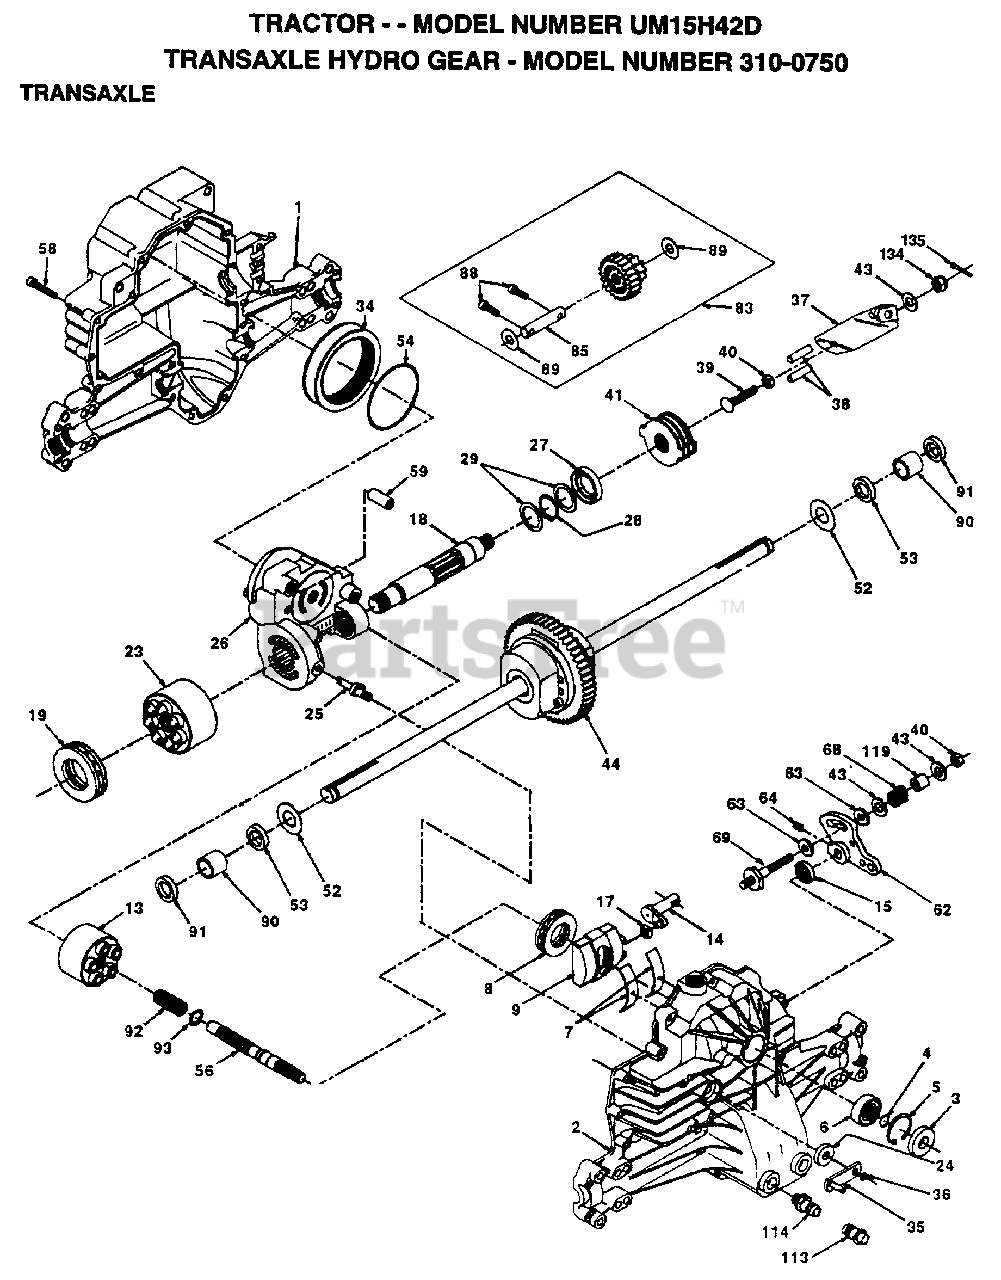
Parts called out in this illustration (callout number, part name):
1	HOUSING.L.50074RM
2	HOUSING.UP.70125
3	SEAL.9008000-0128
4	RING.RET.2003016.
5	RING.RET.2003052.
6	BEARING.(50552)42X68X16
7	CRADLE- 2003023.
8	BEARING.2003044.
9	SWASHPLT.2003087.
13	BLOCK.CLYN.70079.
14	ARM.TRUN.2003005.
15	SEAL.9008000-0126
17	GUIDE.2000015.
18	SHAFT.MOTOR.50115
19	BEARING.THS.50019
23	BLOCK.CYLIN.70082
24	SEAL.LIP.45074
25	ACTUATOR.2003555
26	KIT.CENTER.70133
27	SEAL.LIP.45075
28	RING RETAIN 50007
29	WASHER.44872
34	ELEMENT.OIL.44964
35	ARM.BYPASS.50270
36	RING.RETAIN.44870
37	ARM.ACTUAT.23710
38	PIN.ACTUAT.44891
40	NUT.LOCK.HX.50108
41	KIT.BRAKE.70135
43	WASHER HYD 44130
44	DIFFERENTIA.70130
52	WASHER.HYD.50152
53	SEAL.HYDRO.45076
54	O RING.HYD.45077
56	SHAFT.INPUT.50005
58	BOLT.1/4-20.44876
59	PIN.HYDRO.50002
62	ARM.CONTROL.50254
63	PUCK.DAMPER.50281
64	SCREW.SET.50018.
68	SPRING.HYD.50277
69	STUD.5/16-24.DANA
83	JACKSHAFT/PINION GEAR.70132
85	JACKSHAFT.50086
88	SCREW.CAP.50154.
89	WASHER.HYD.50132
90	BEARING.SLV.50118
91	SEAL.WIPER.50941
92	SPRING.2003014.
93	WASHER.2003017
113	CAP.VENT.70109
114	O-RING.ASM.70110
119	SPACER.HYD.50278
134	NUT.CAS.HYD.44142
135	PIN.COT.HYD.44101
